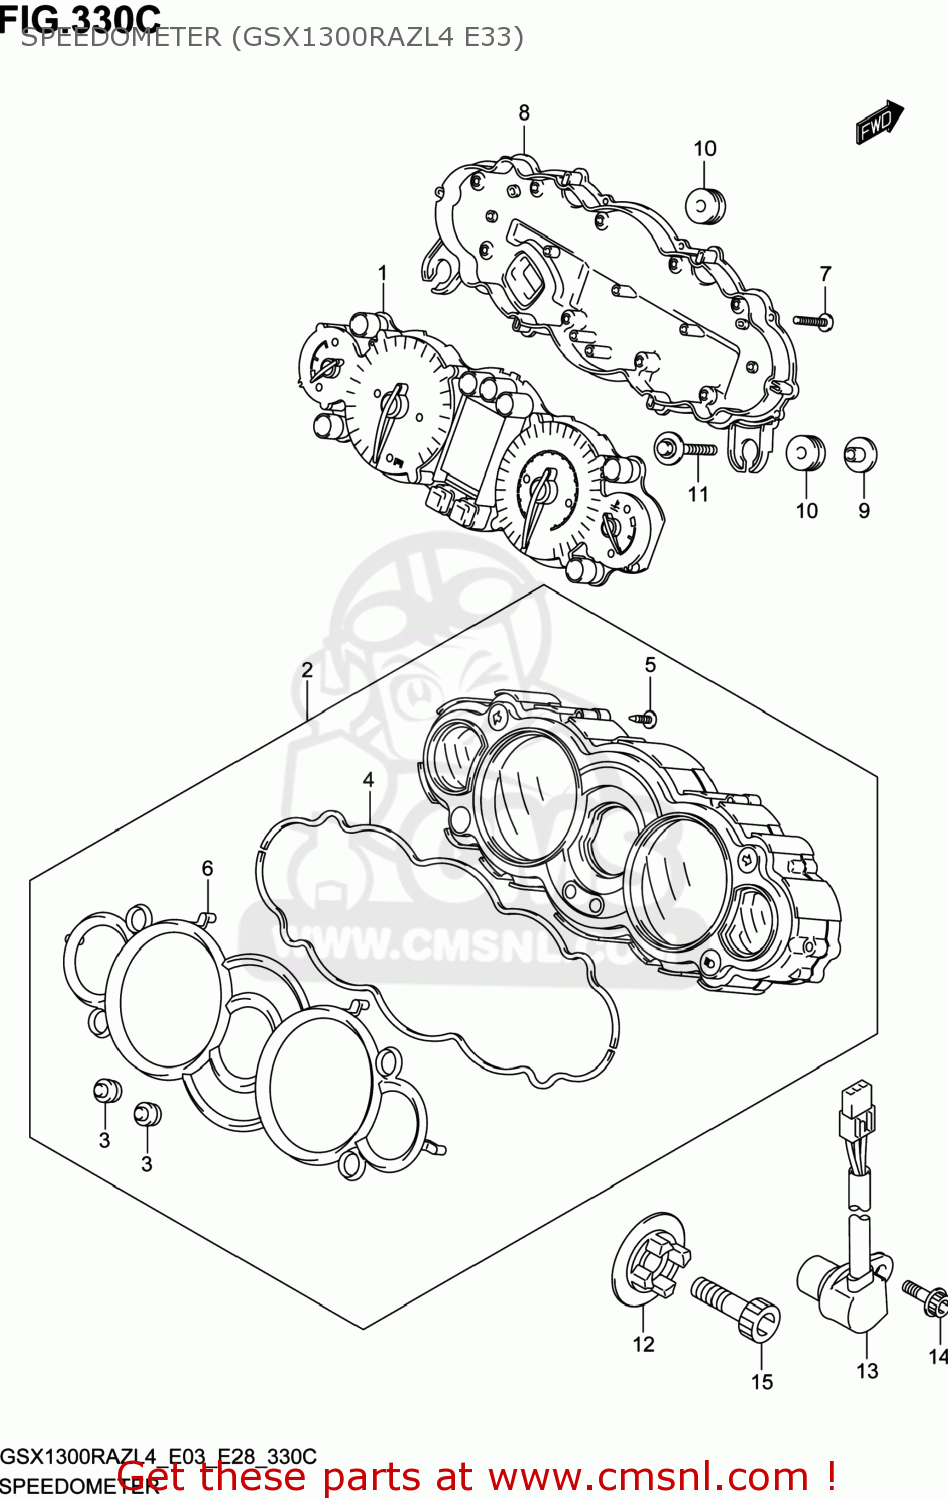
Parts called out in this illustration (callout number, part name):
1	COMBINATION METER
2	UPR CASE
3	RUBBER,SWITCH
4	PACKING (NAS)
5	SCREW(2.3X8)
6	RING
7	SCREW(3X16)
8	LWR CASE
9	WASHER
10	CUSHION
11	BOLT(6X25)
12	ROTOR,SPEED
13	SENSOR,SPEED
14	BOLT
15	BOLT
